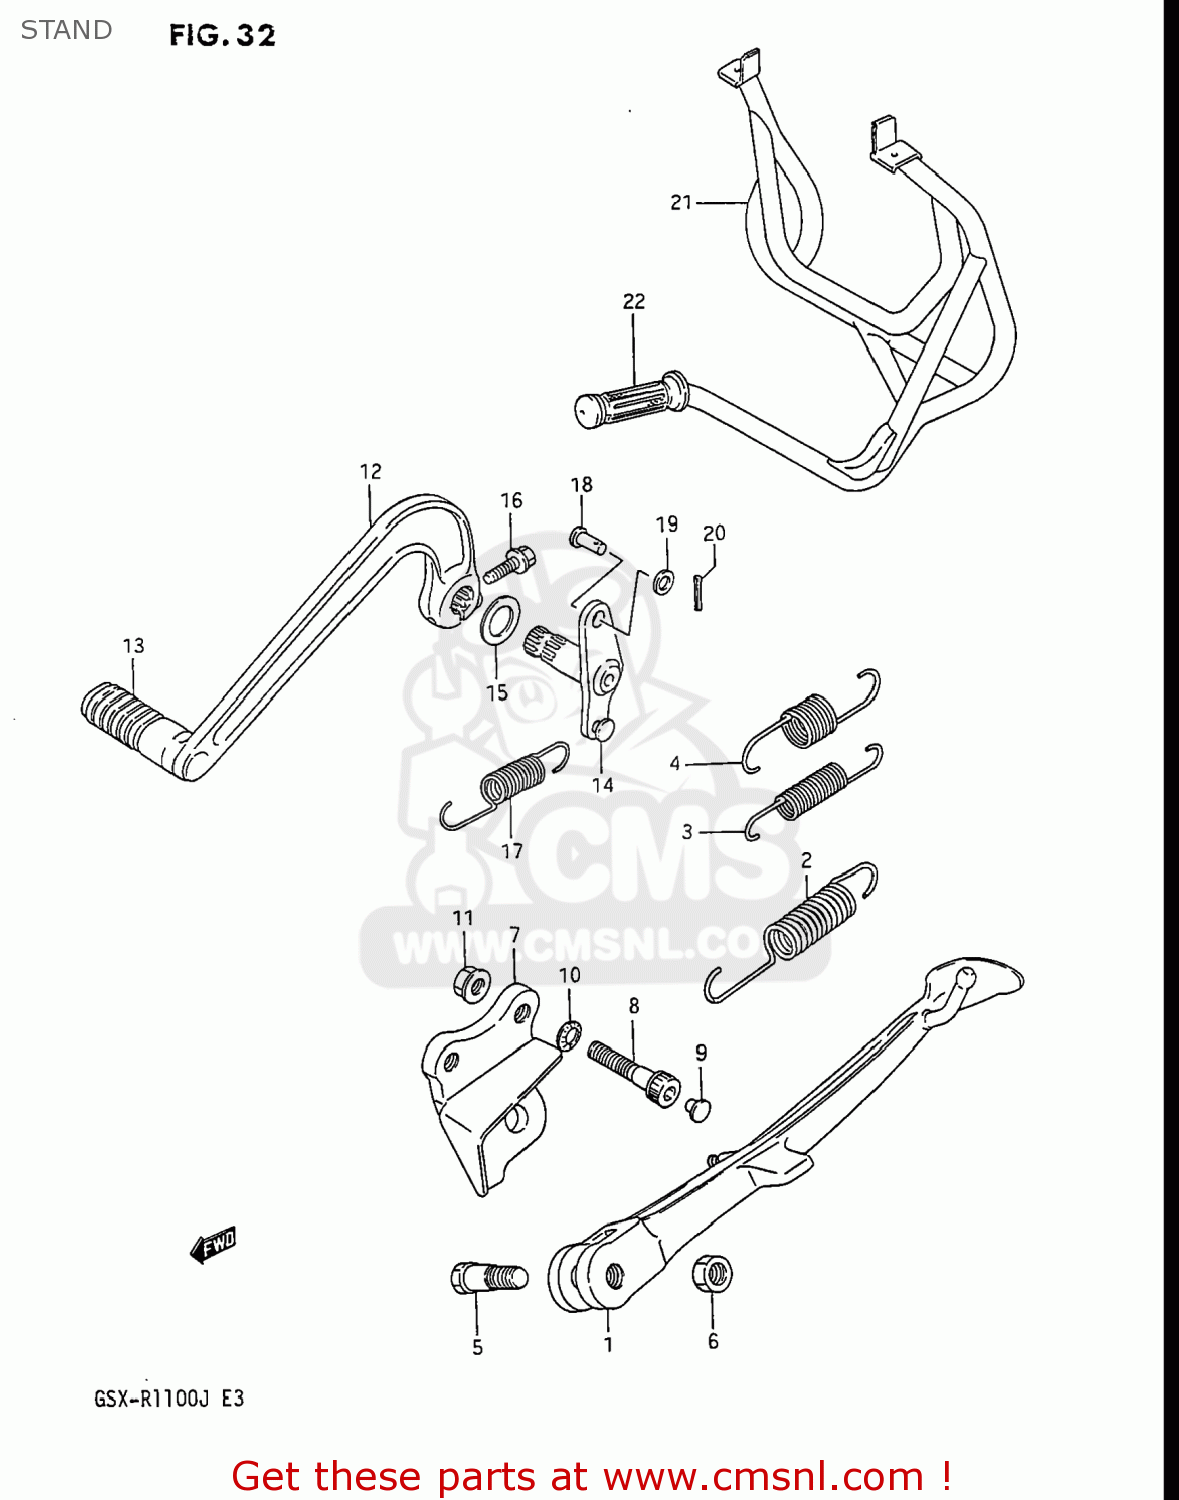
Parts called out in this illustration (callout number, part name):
1	STAND,PROP
2	SPRING
3	SPRING
4	SPRING
5	BOLT(10X38)
6	NUT
7	BRACKET,PROP STAND
8	BOLT, FRONT RH
9	CAP,ENGINE MOUNTING
10	WASHER
11	NUT
12	PEDAL,BRAKE
13	RUBBER,BRAKE PEDAL
14	ARM COMP,BRAKE ROD
15	WASHER,BRAKE PEDAL
16	BOLT
17	SPRING
18	PIN
19	WASHER
20	PIN
21	STAND,CENTER
22	GRIP,L
